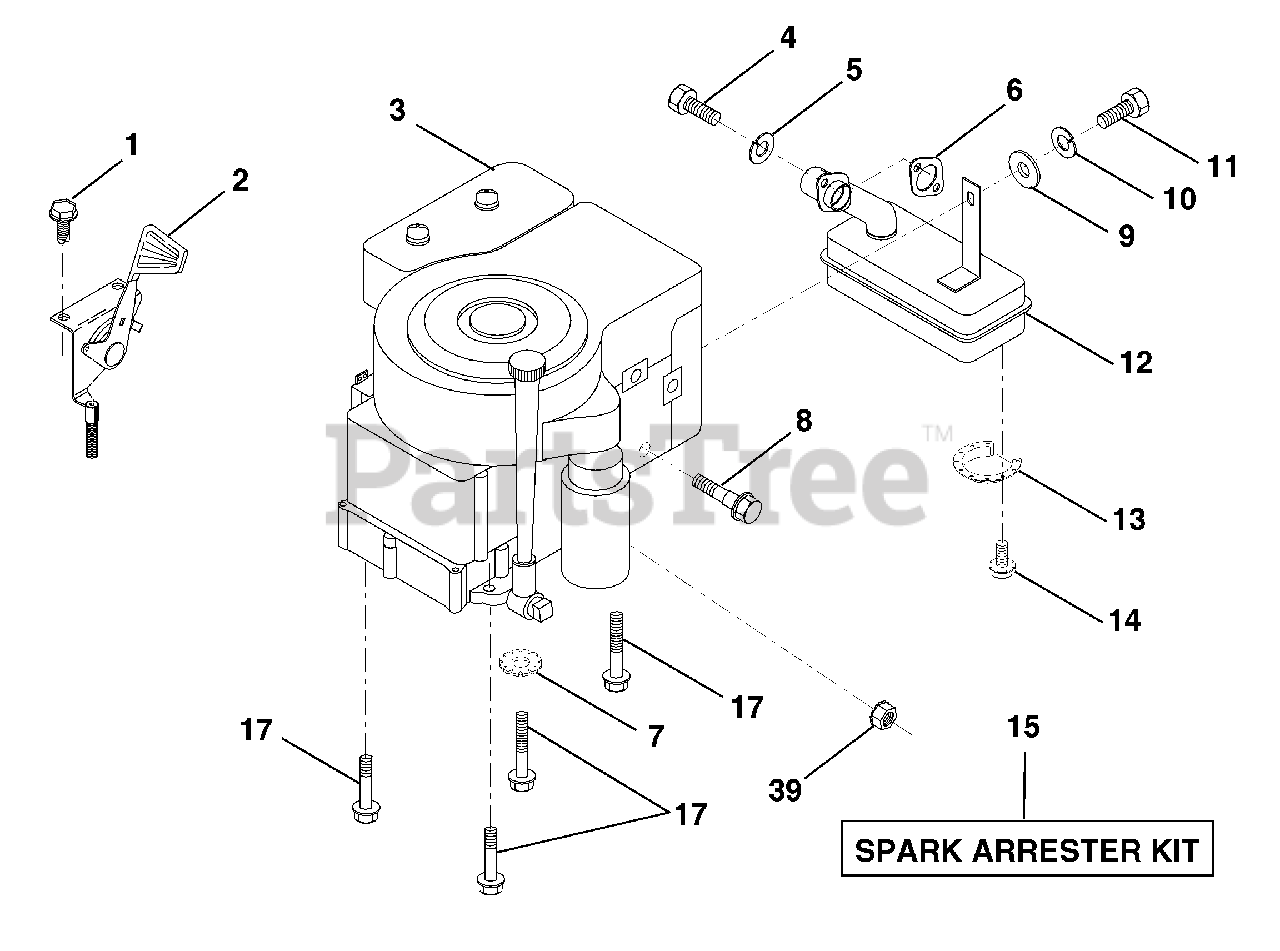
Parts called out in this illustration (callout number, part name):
1	Screw, Hex Thd. Cut 1/4-20 x 1/2
2	Control, Throttle
3	Engine
4	Screw, Hex, Cap 5/16-18 x 3/4
5	Washer, Lock Hvy Hcl Spring 5/16
6	Gasket, Exhaust
7	Washer Lock Ext. Tooth 3/8
8	Bolt, Shoulder 5/16
9	Washer 5/16 x 3/4 x 16
10	Washer, Lock Hvy Hlcl Spring 1/4
11	Bolt, Hex Fin.
13	Deflector, Muffler
14	Screw, Spiderlock, Hex Hd 8 x 1/2
15	Arrester, Spark
17	Screw, Hex Washer Head, Thdrol. 3/8-16 x 1-1/2
39	Nut, Flange 1/4-20
